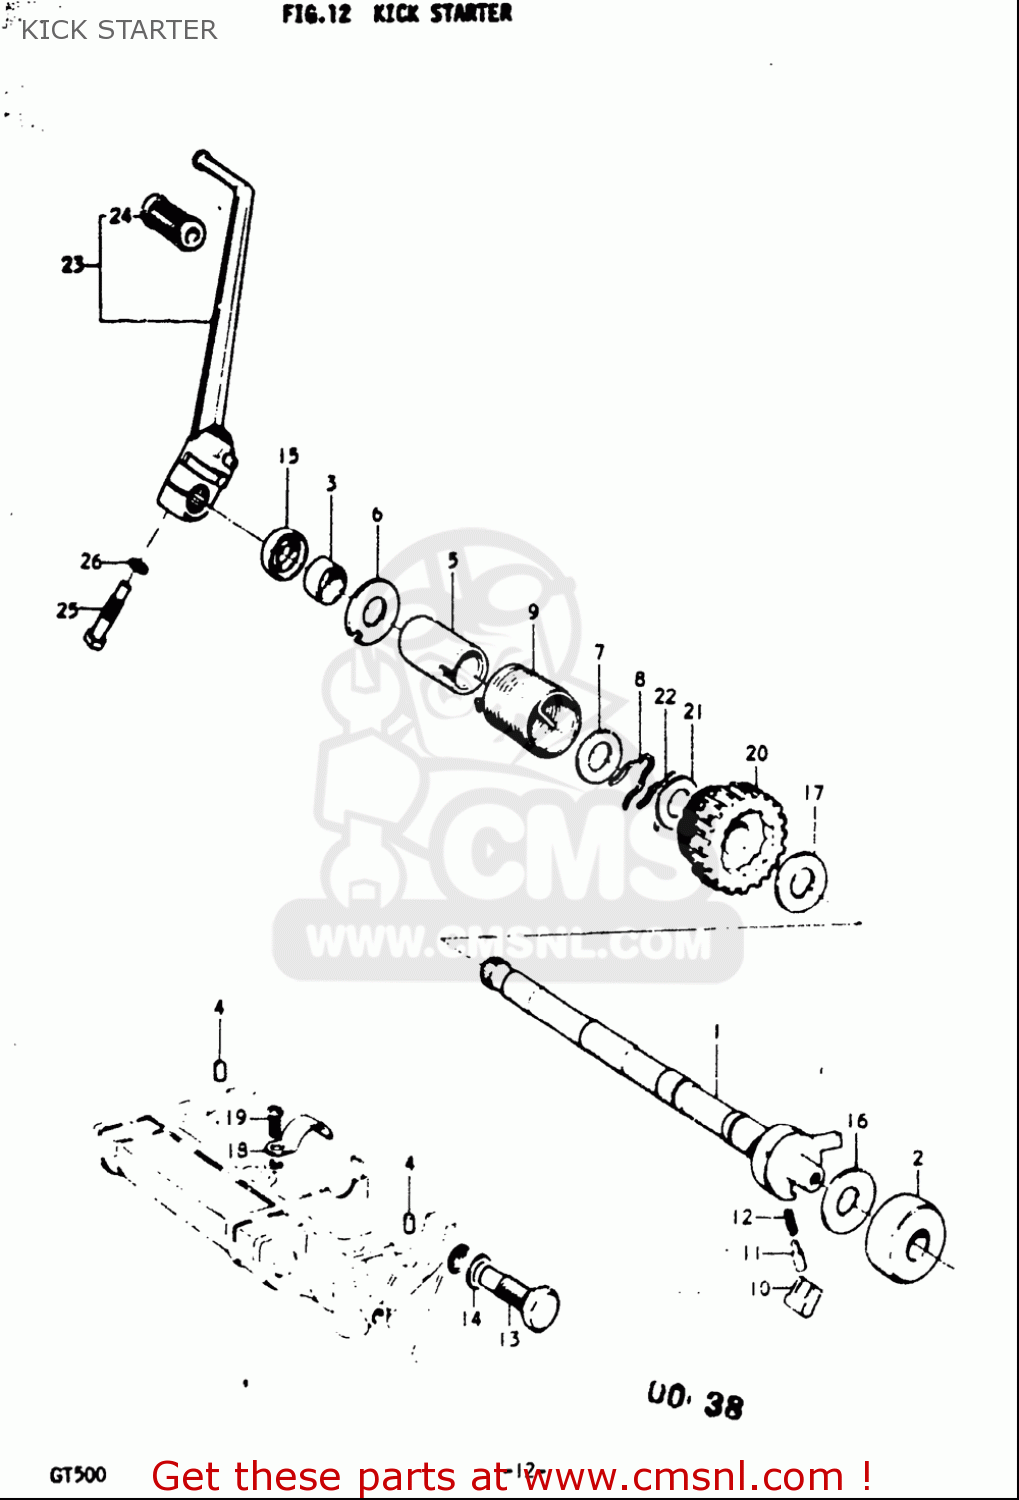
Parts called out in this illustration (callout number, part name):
4	PIN
7	WASHER(16X30X1)
9	SPRING
10	PAWL,KICK STARTER
11	PIN(5X15.5)
12	SPRING
14	WASHER(14.5X22X1.6)
15	SEAL,OIL(16X30X8)
16	WASHER(13X31.5X1.5)
19	SCREW
21	WASHER(16X30X1)
24	RUBBER,KICK STARTER PEDAL
25	BOLT(10X37.5)
26	WASHER,LOCK
